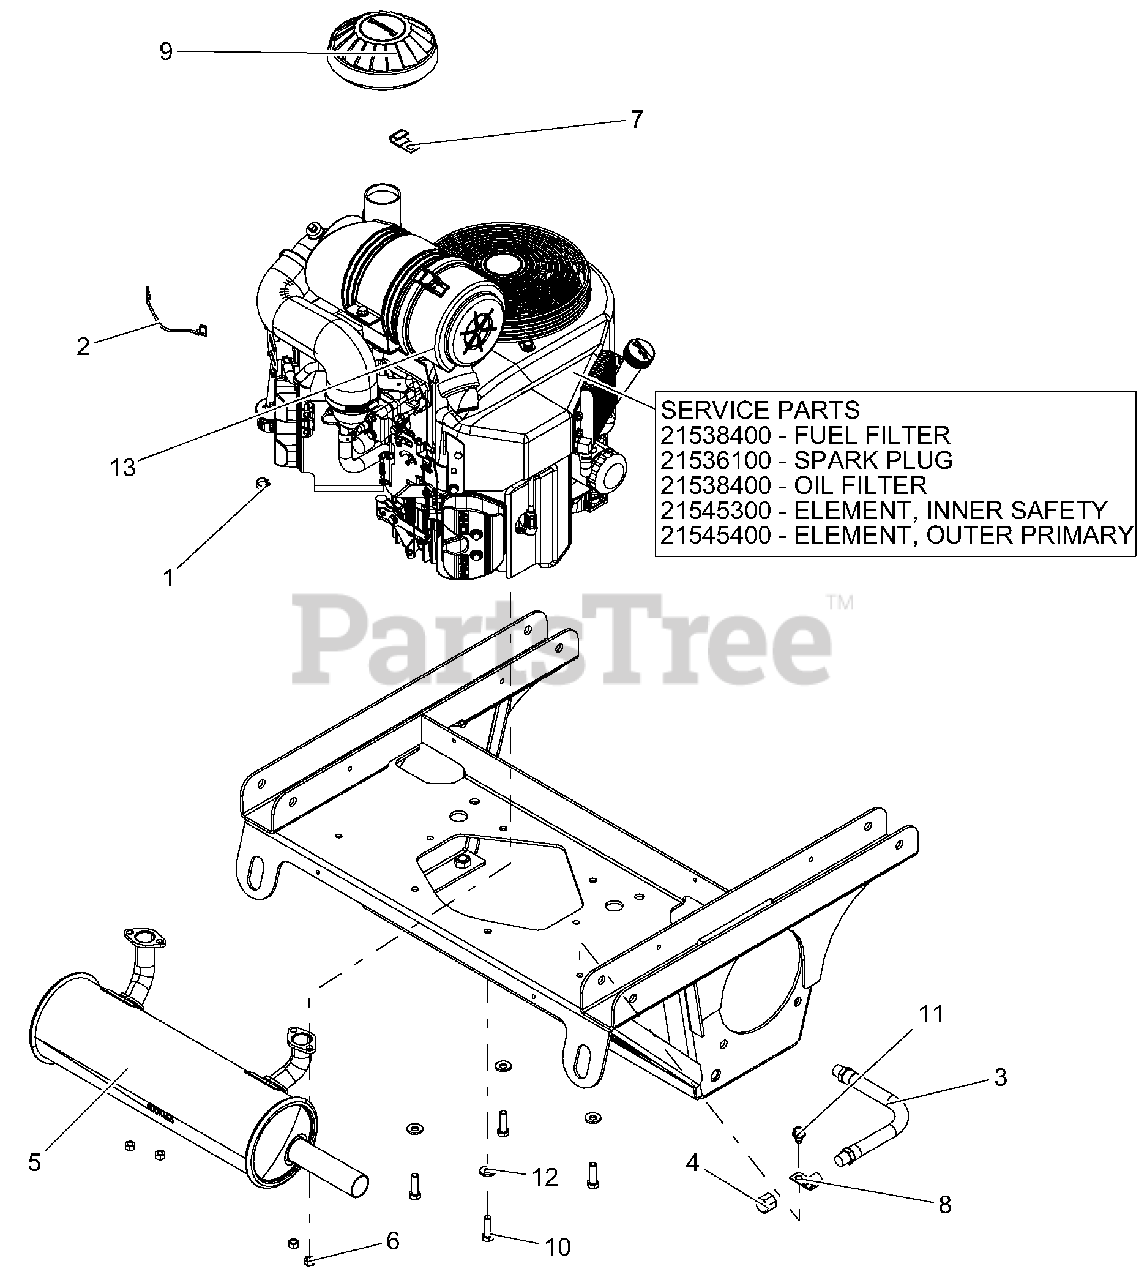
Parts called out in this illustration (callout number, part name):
1	CLAMP, FUEL LINE
2	LEAD - STARTER SOLENOID
3	HOSE, HYD .38-11-0K M6N0-M6NO
4	PIPE, CAP 3/8 NPT FEMALE
5	MUFFLER, 27-31 FX KAW
6	NUT-LK-TOP M8-1.25 YWZC
7	CLAMP, J
9	CAP, AIR CLEANER INTAKE (2")
10	BLT-HEX .38-16X1.25 GR5 YWZC NYTORQ
11	SCR-TAP .38-16X.50 HWH TR YWZ
12	WSHR, 3/8" SPRING DISC
13	ENGINE, KAWASAKI FX850
